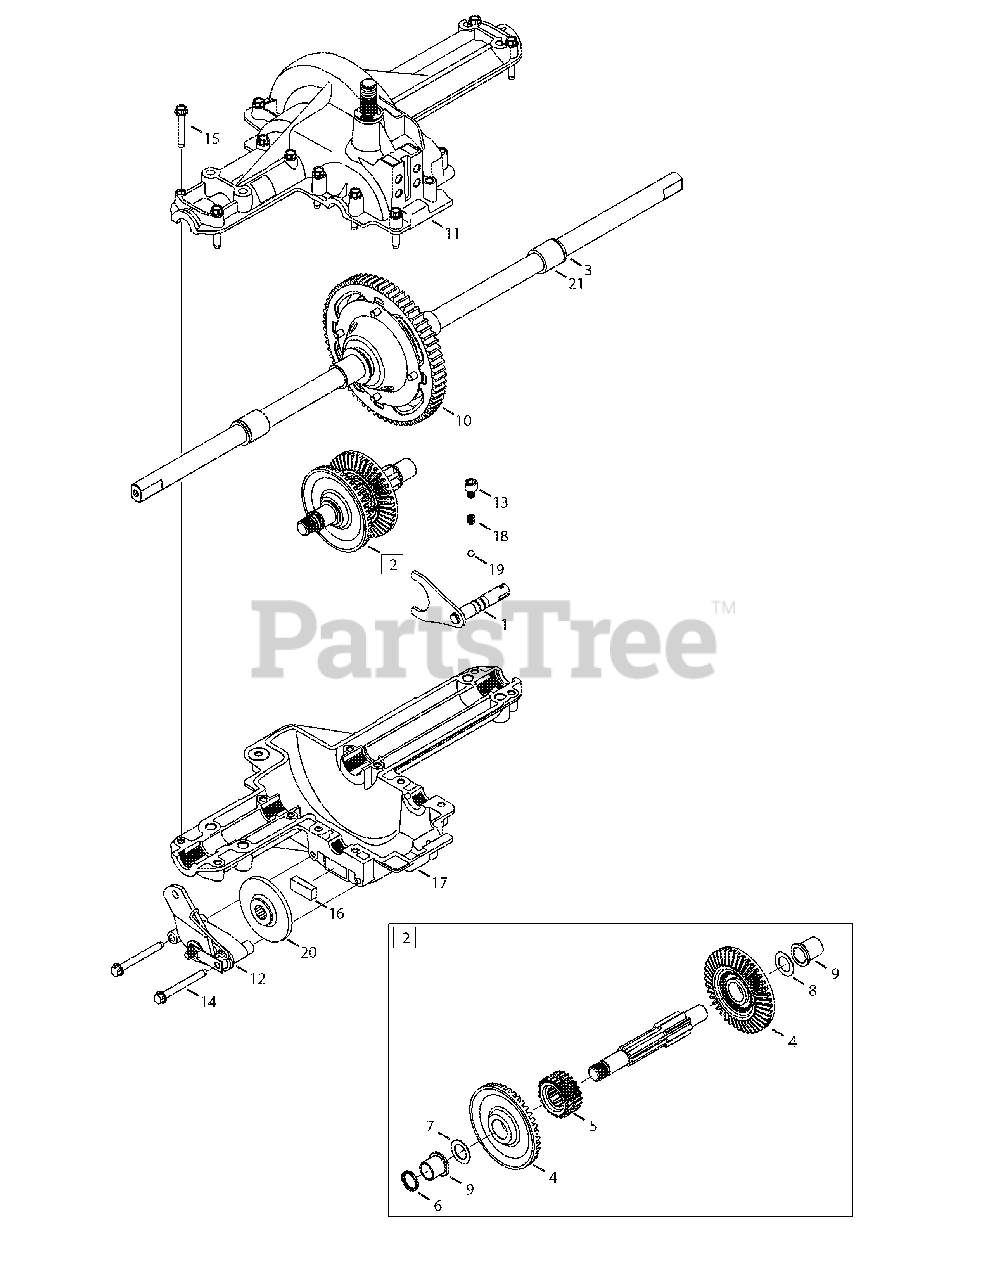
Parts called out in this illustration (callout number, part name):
1	Detent Shaft Assembly
2	Drive Shaft Assy.
3	Seal,.75 x 1.0 x.125
4	Bevel Gear, 42 tooth spline
5	Single Speed Clutch Collar
6	Seal, .625 x .812 x .094
7	Flat Washer 5/8 x 1 x .030
7	Flat Washer .634 x 1 x .04
7	Flat Washer .63 x 1 x .02
7	Flat Washer .632 x 1 x .035
7	Thrust Washer 1.00 x .632 x .0
8	Flange Bearing, 5/8 x 3/4 x 3/4
9	Flange Bearing, 5/8 x 3/4 x 15/16
10	Differential Assembly
11	Upper Housing
12	Brake Assembly
13	Self-tapping Screw, 5/16-18 x .375
14	Self-tapping Screw, 1/4-20 x 2.375
15	Self-tapping Screw, 1/4-20 x 1.625
16	Brake Puck
17	Lower Housing
18	Compression Spring
21	Sleeve Bearing,.75 x.1.0 x 1.0
